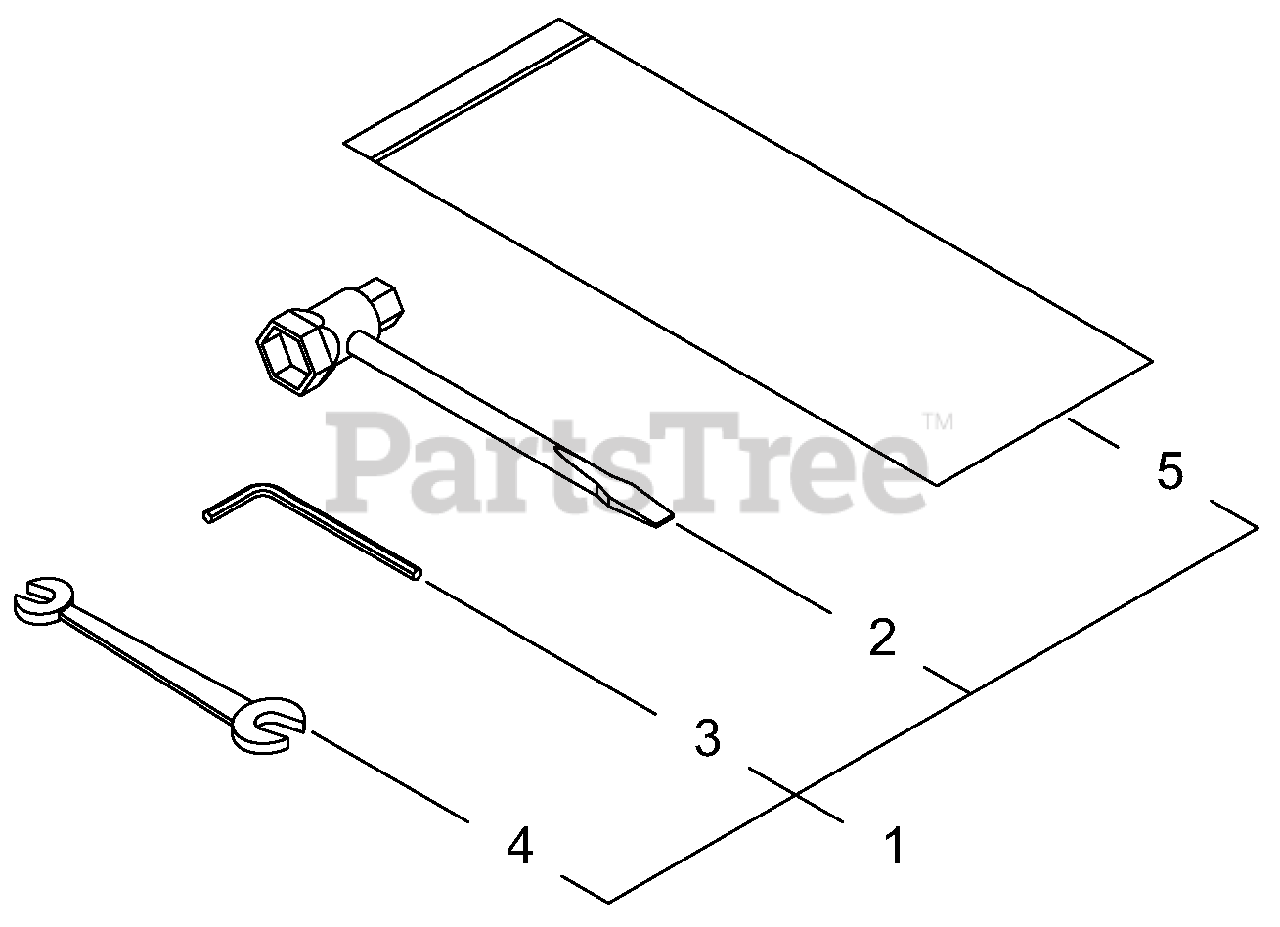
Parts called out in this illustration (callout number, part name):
1	TOOL KIT
2	T-WRENCH - 13X19mm
3	HEX KEY - 4mm
4	SPANNER - 8X10mm
5	BAG, TOOL
